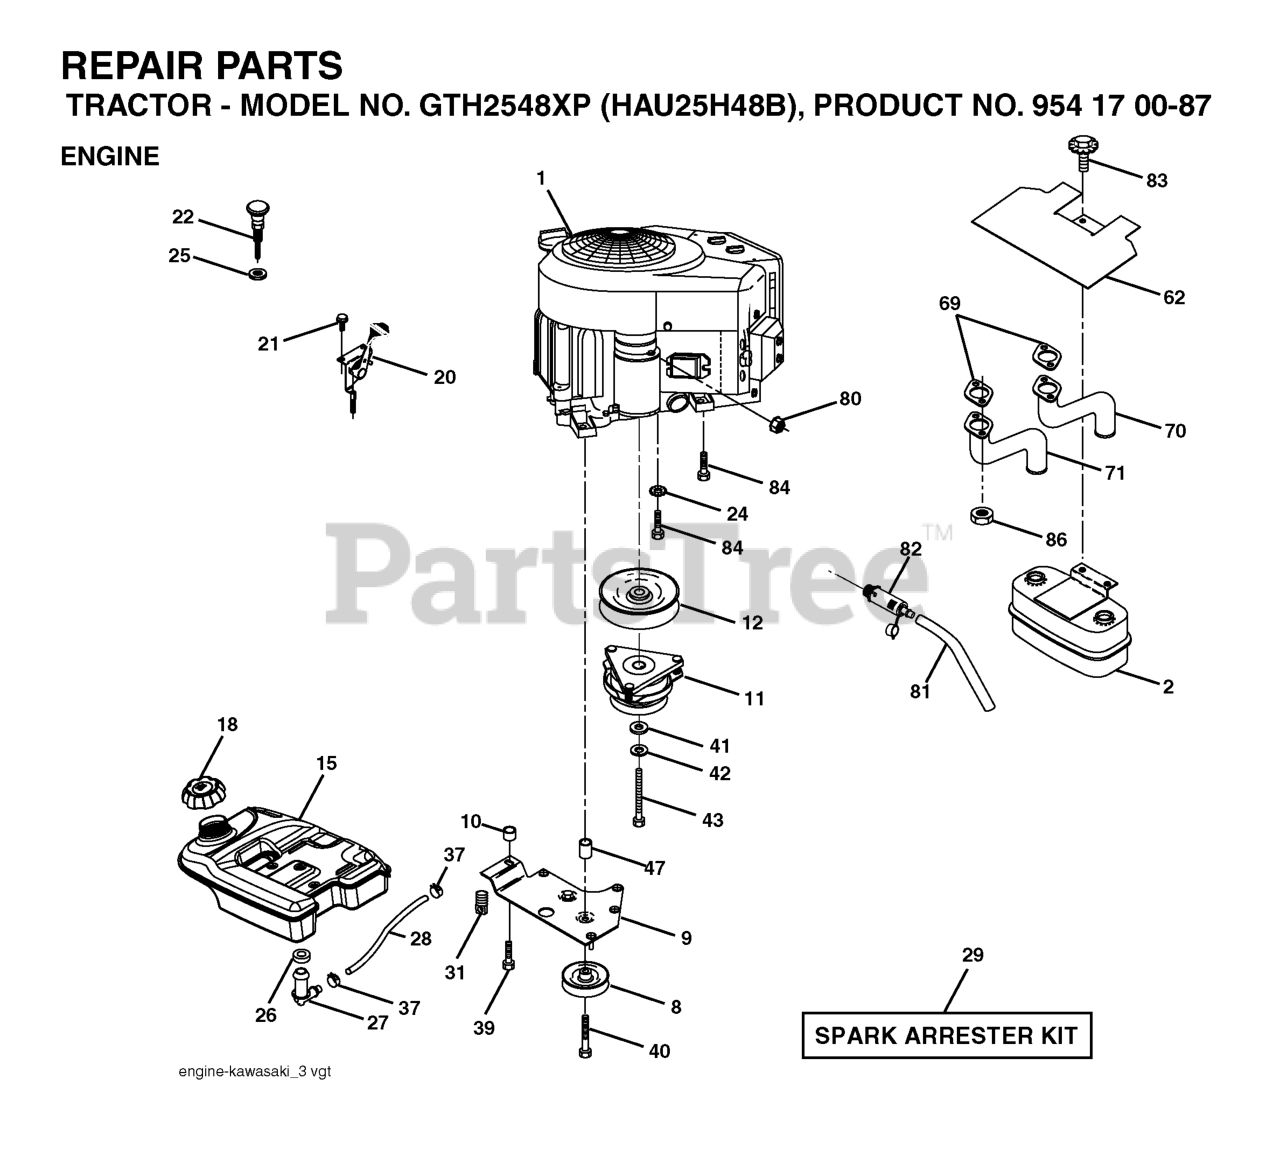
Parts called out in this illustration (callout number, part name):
2	MUFFLER.TWIN.CYL.LOW.TONE
8	RP.IDLER GROOVED
9	KEEPER ASM BELT ENGINE
11	CLUTCH MZ ZTR GT.48/54"1.125"
12	PULLEY ENG VGT ELECT CLUTCH
15	TANK.FUEL.5.0 LEFT.FILL.YTGT
18	TANK CAP
20	CONTROL.THROTTLE.COBRA.42"BLK.
21	SCREW
22	CHOKE CONTROL
24	LOCKWASHER
25	Nut Keps 3/8 - 24 UNF
26	BUSHING OUTLET T
27	STEM FUEL TANK
29	KIT.SPARK ARRESTOR 794945 B&S
37	HOSE CLAMP
39	SCREW TT 3/8-16X2-1/4 UNC
40	Screw TT 3/8-16 x 4 unc
42	LOCKWASHER
43	BOLT HEX 7/16-20 X 3.75 GR. 5
62	HEAT SHIELD
70	TUBE.EXHAUST.KAWASAKI.RH
71	TUBE EXHAUST LH
80	FLANGE NUT
81	TUBE, DRAIN OIL ASM.
83	BOLT.5/16-18UNCX3/4 W/SEMS.BLK
84	SCREW 3/8-16 X 1-1/2
86	NUT.HEX.FLANGE.TOPLOCK
